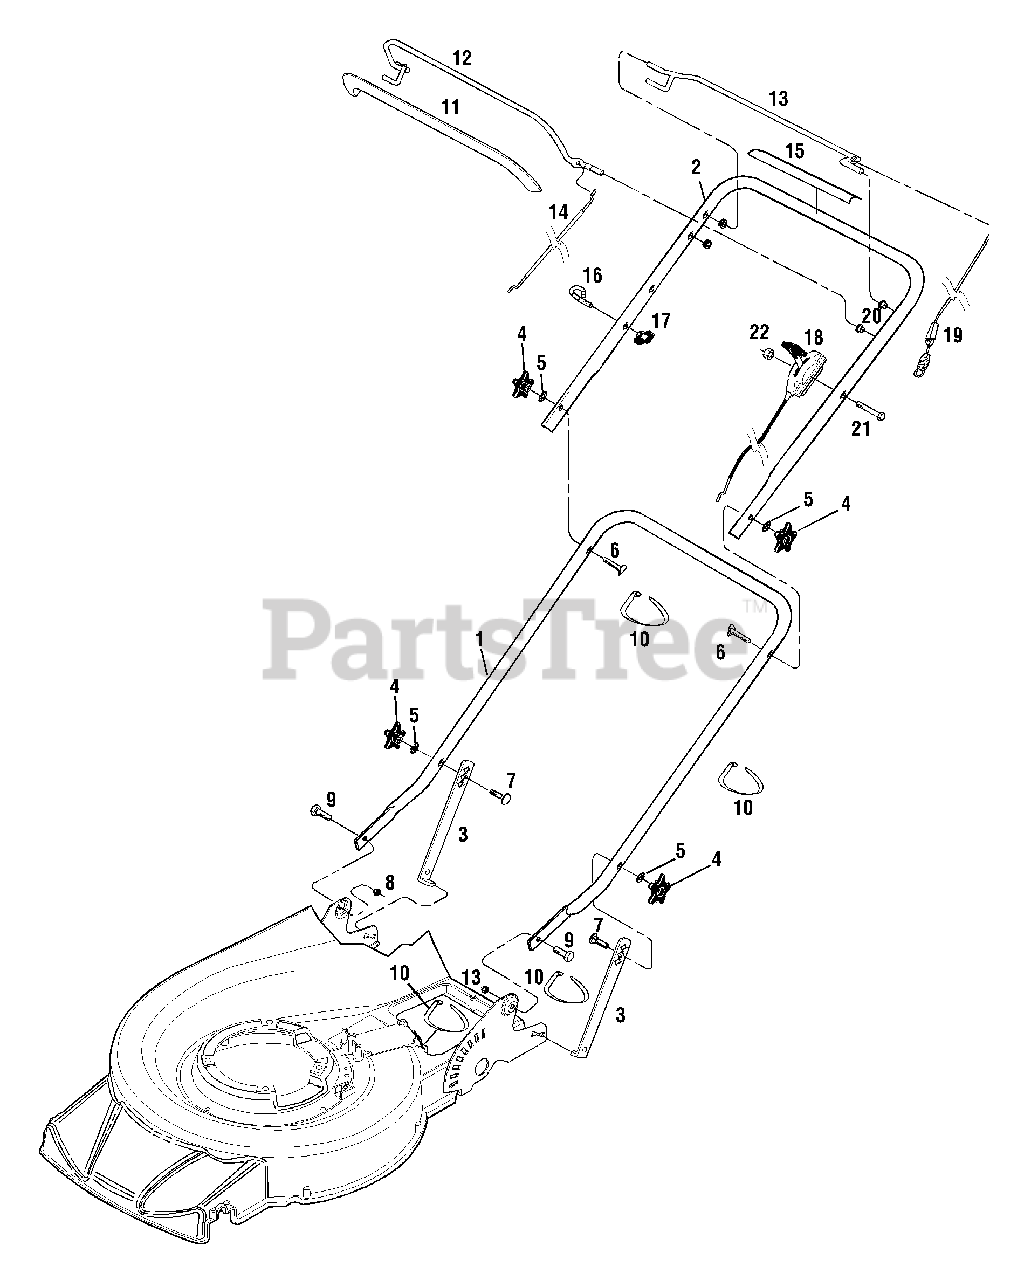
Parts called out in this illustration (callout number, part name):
1	Lower Handlebar
2	Upper Handlebar
3	Handlebar Support Strut
4	Handlebar Adjustment Knob
5	Ext. Tooth Lock Washer, 5/16
6	Curved Head Screw, 5/16-18 x 1-3/4
7	Carriage Bolt, 5/16-18 x 1-3/4, Special
8	Hex Lock Nut, 3/8-16
9	Hex Hd. Screw, 3/8-16 x 3/4, GR. 5
10	Cable Tie
10	Bushing, Nyliner
11	Bail Grip
12	Operator Presence Control Bail
13	Wheel Drive Bail
14	Operator Presence Control Cable
15	Decal - Bail Operating Instructions
16	Rope Guide
17	Wing Knob, 1/4-20
18	Speed Control Lever/Cable
19	Drive Control Cable
21	Hex Hd. Screw, M6
22	Hex Nut, M6
